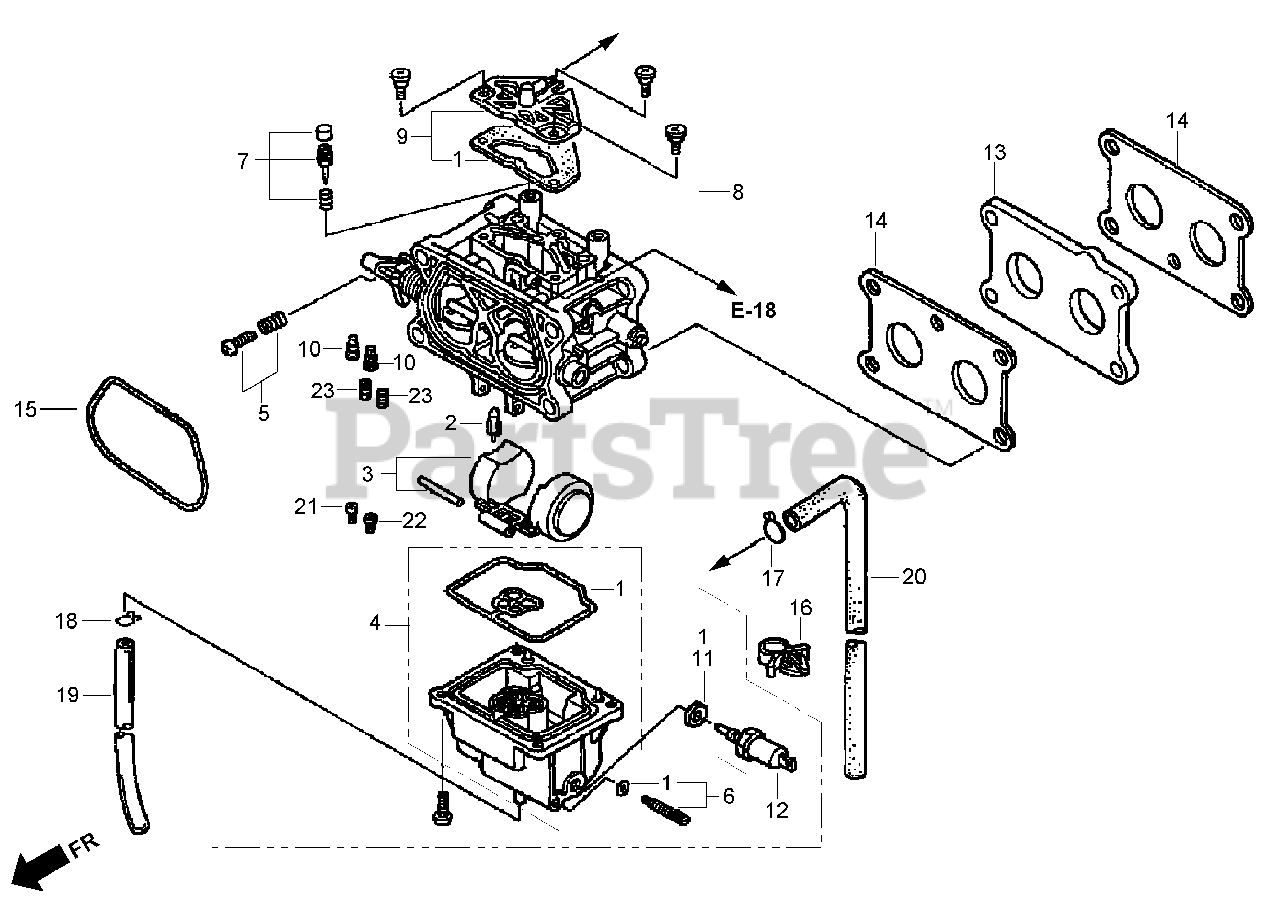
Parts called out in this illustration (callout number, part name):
1	GASKET SET
2	VALVE-FLOAT
3	FLOAT SET
4	FLOAT CHAMBER SET
5	SCREW-SET
6	SCREW-SET, DRAIN
7	SCREW SET, PILOT
8	CARBURETOR ASM (BW02C A)
9	AIR VENT COVER SET
10	CAP
11	GASKET
12	SOLENOID VALVE ASM
13	INSULATOR-CARBURETOR
14	GASKET-INSULATOR
15	GASKET-CLEANER, AIR
16	CLIP-HARNESS, WIRE
17	CLIP-TUBE (B8)
18	CLIP-TUBE (B6.5)
19	HOSE-BULK, VINYL (4X7X8000) (4X7X300)
20	HOSE-BULK, VACUUM (45X1000) (45X400)
21	JET-MAIN (No. 82.5)
21	JET-MAIN (No. 85)
21	JET-MAIN (No. 87.5)
22	JET-MAIN (No. 85)
22	JET-MAIN (No. 87.5)
22	JET-MAIN (No. 90)
23	JET-PILOT (No. 37.5)
